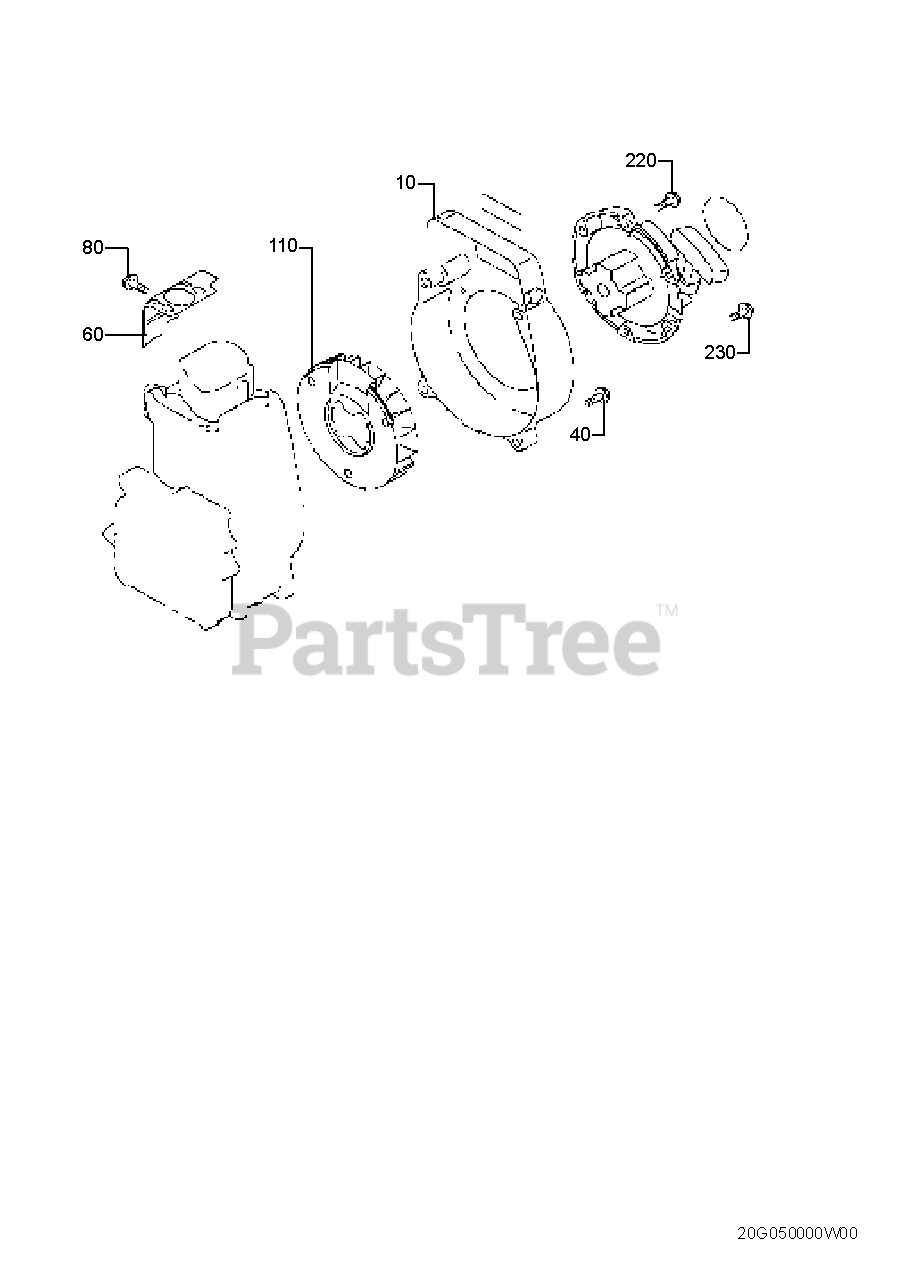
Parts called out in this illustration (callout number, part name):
10	BLOWER HOUSING CP
60	CYLINDER BAFFLE
110	COOLING BLOWER
